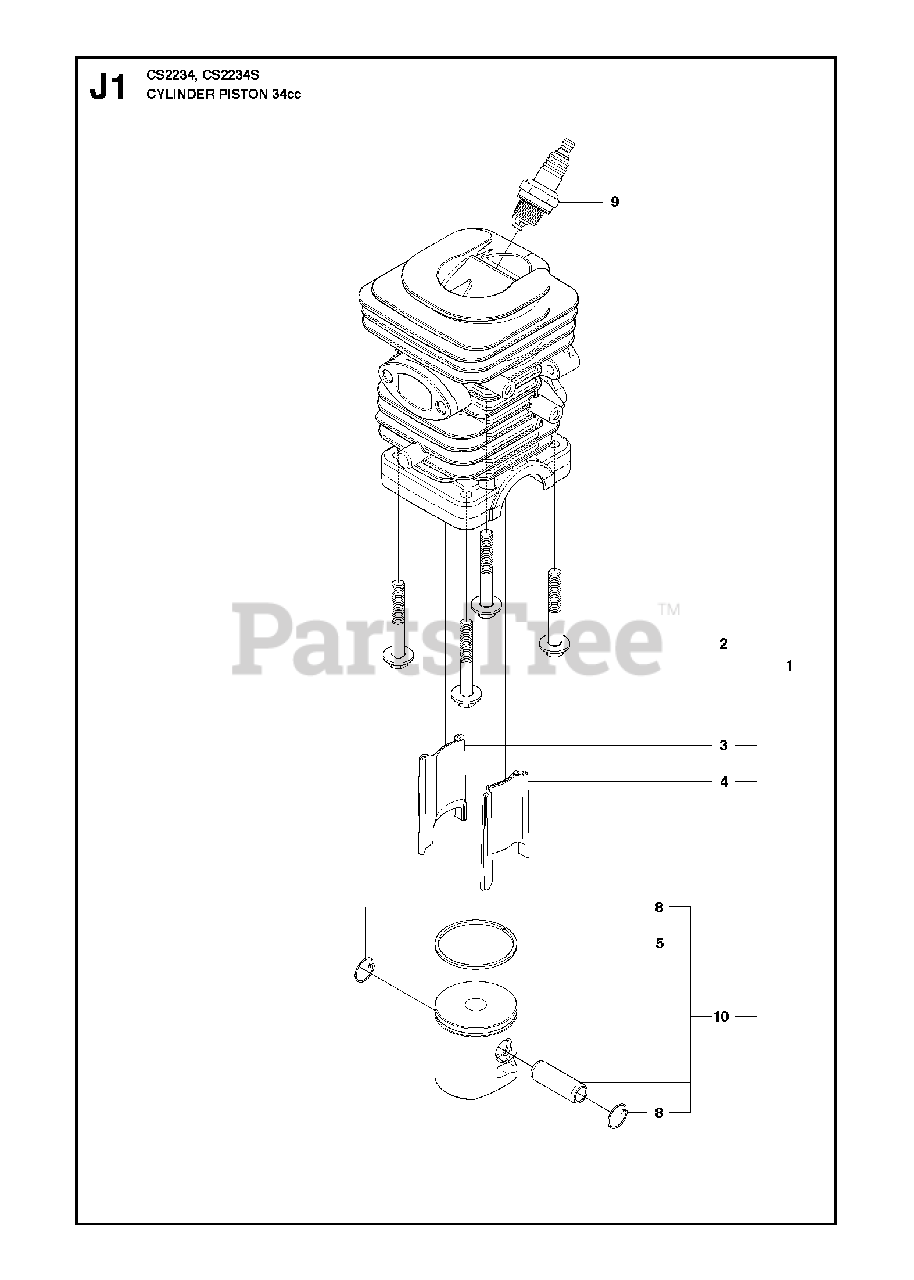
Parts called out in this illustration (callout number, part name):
1	KIT, CYLINDER & PISTON
2	BOLT
3	TRANSFER INSERT LEFT
4	TRANSFER INSERT RIGHT
5	PISTON RING
8	C-CLIP,PSTN PIN 36/41
9	SPARK PLUG RCJ7Y
10	PISTON KIT
